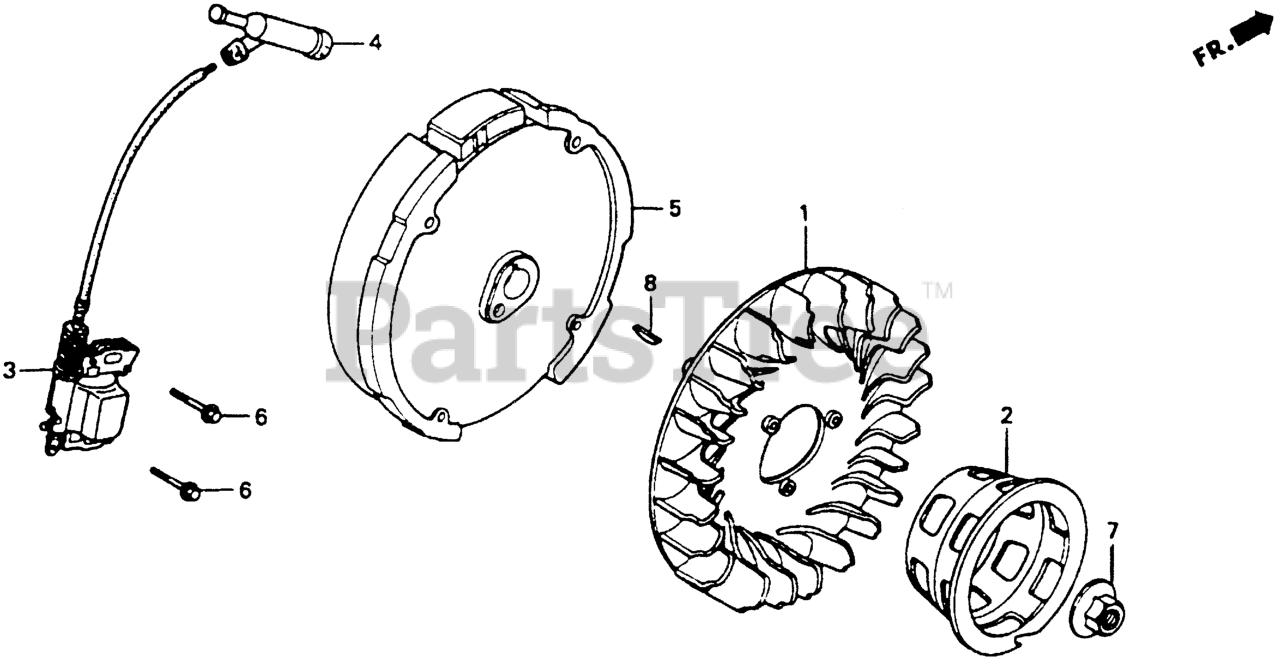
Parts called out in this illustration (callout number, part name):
1	FAN, COOLING
2	PULLEY, STARTER
3	COIL ASSY., IGNITION Use up to Engine SN 1530314.
4	CAP ASSY., NOISE SUPPRESSOR (Honda Code 3526837). (NICHIWA Y-EZ RTFM256)
5	FLYWHEEL
6	BOLT, FLANGE (6X28) (CT200) Use up to Engine SN 1530314.
6	BOLT, FLANGE (6X25) Use up to Engine SN 2056819.
7	NUT, SPECIAL (14MM)
8	KEY, SPECIAL WOODRUFF (25X18)
